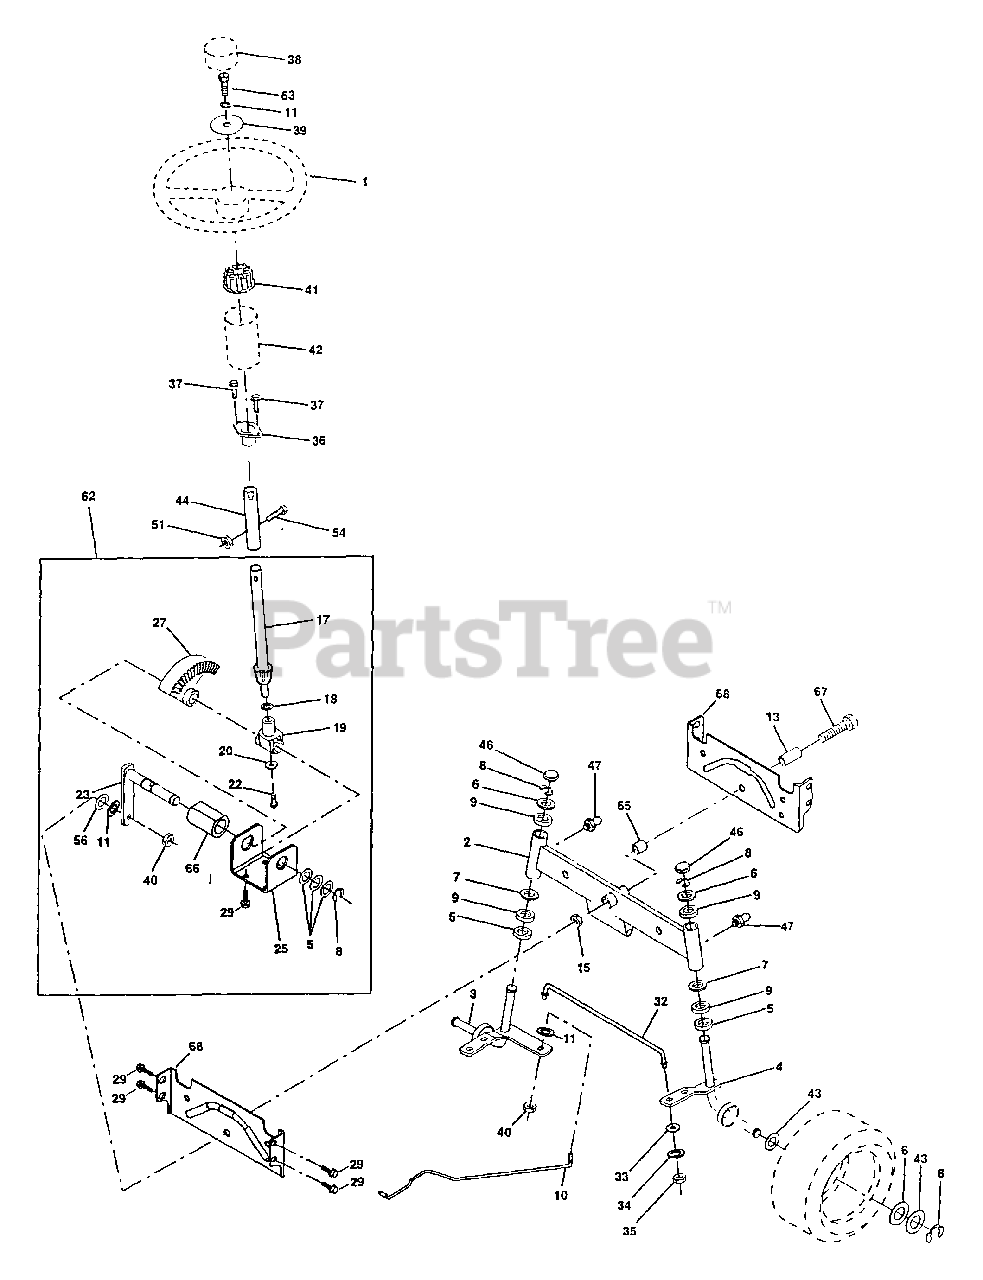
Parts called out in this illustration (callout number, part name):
1	Wheel Steering (AYP part number)
2	Axle Asm Stmp Dropped STLT (AYP part number)
3	Spindle Asm LH
4	Spindle Asm RH
5	Bearing Race Thrust Harden
6	Washer 25/32 X 1-5/8 X 16 Ga
7	Washer 27/32 X 1-1/4 X 16 Ga
8	Ring Klip #t5304-75
9	Bearing Col Strg Blk
10	Link Drag Extended Stamped
11	Washer Lock Hvy Hlcl Spr 3/8
13	Bearing Axle STLT/GT
15	Nut Lock Flange 5/8-11 Unc
17	Shaft Asm Strg
18	Washer Thrust 515 x 750 x 033
19	Support Shaft (AYP part number)
20	Washer Shim 1/4 X 5/8 X 062 (AYP part number)
22	Screw Hex Socket 1/4-20 x 5/8 (AYP part number)
23	Shaft Asm Pittman (AYP part number)
25	Bracket Steering
27	Gear Sector
29	Screw Thdrol 3/8-16 x 3/4 Ty-tt
32	Rod Tie Ball J Adj VGT (AYP part number)
33	Washer 11/32 x 3/4 x 16 Ga.
34	Washer Lock Hvy Hlcl Spr 5/16
35	Locknut 5/16-24 Unf 3847
36	Bushing Strg (AYP part number)
37	Screw
38	Insert Cap Strg Wh Au
39	Washer 13/32 X 2-3/8 X 8 Ga
40	Lock nut
41	Adaptor Wheel Strg
42	Boot Steering Dash
43	Washer 25/32 X 1-1/4 X 16 Ga
44	Extension Steering Shaft LR/LT (AYP part number)
46	Cap Spindle Fr Top Blk
47	Fitting Grease
51	Nut Lock Hex w/Ins 5/16-18
54	Bolt Fin Hex 5/16-18 Unc x 1-1/4
62	Kit, Steering Assembly Svc
63	Bolt Fin Hex 3/8-16 unc x 1 Gr. 5
65	Spacer Axle
66	Bearing Arm Pittman
67	Bolt, Fin Hex 5/8-11 UNC x 2-3/4
68	Axle, Brace
